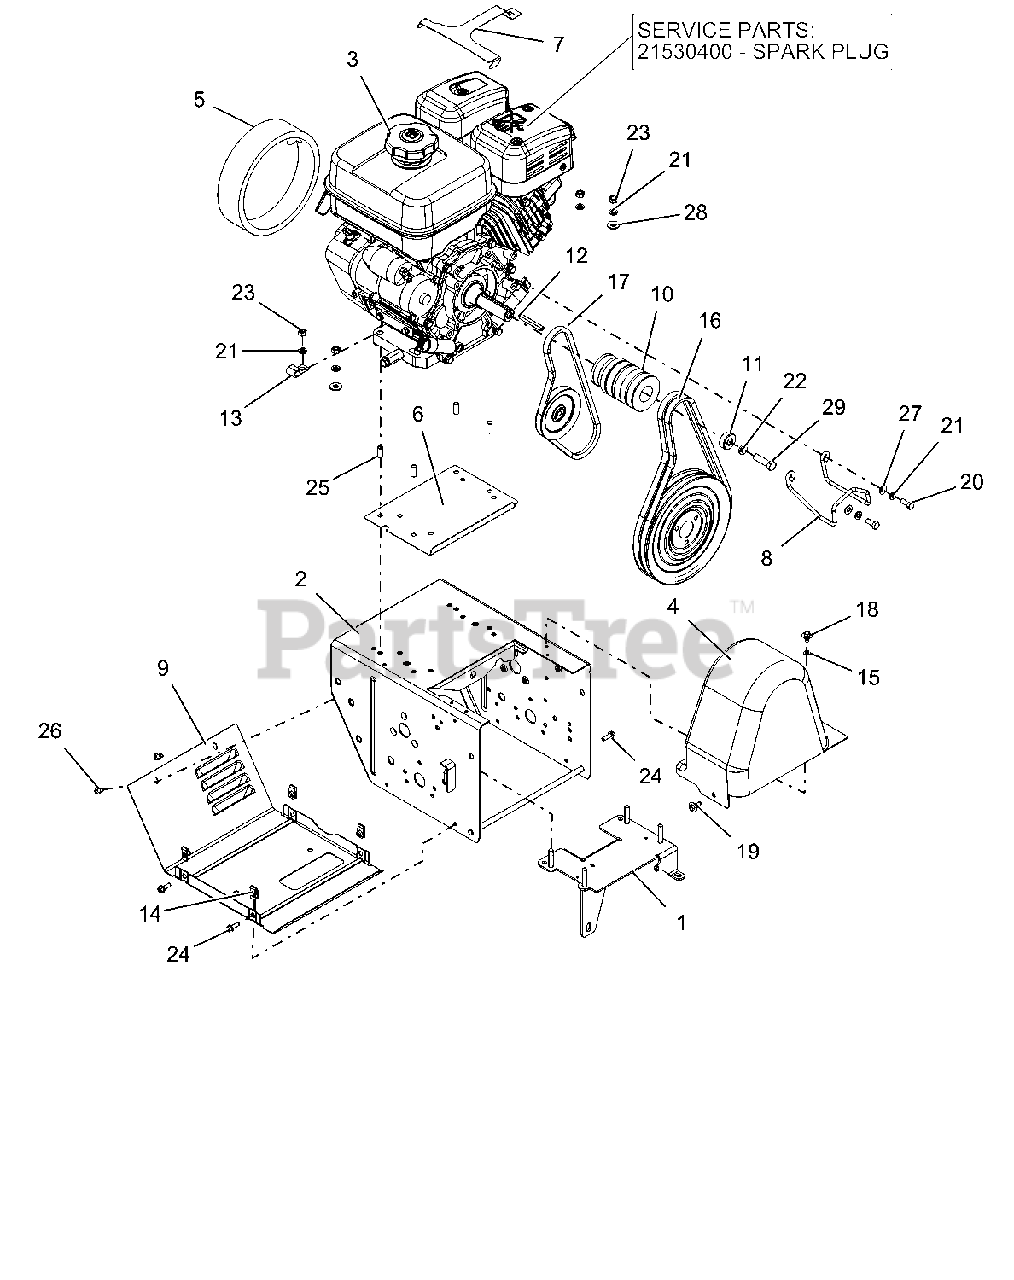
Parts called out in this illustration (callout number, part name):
1	BRKT, HYDRO TRANS LG
2	FRAME, MAIN - PRO SNOW
3	PLUG, SPARK - TEC. SNO-THRO
3	ENGINE,SUBARU EX30 AS 12V
4	COVER, BELT-TALL PRO
5	FOAM COVER, RECOIL-SUBARU
6	BAFFLE, WATER-PRO SERIES
7	GUARD, SNOW-SUBARU
8	FINGER, BELT
9	COVER, BOTTOM - VENTILATED
10	SHEAVE, COMBO HYDRO BRUSH
11	BSHG-SPACER .47X1.25X.50
12	KEY .25X.25X2.25
14	NUT-RTNR .25-20X.56
15	NUT-PUSH .25X.50 O.D.
16	V-BELT, HA-RAW EDGE (SET)
17	V-BELT, 4L-WRAPPED
18	SCR-TAP .25-20X.50 LGHWH TR YZ
19	SCR-TAP .25-20X.5 CAPTIVE
20	BLT-HEX .31-24X.75 YWZC GR5
21	WSHR-LK .312X.097 HVY YWZC
22	WSHR-LK .44X.109 REG YWZC
23	NUT-HEX .31-18 YWZC
24	BLT-HEX .25-20X.75 HWH YZ GR5
25	BSHG-SLV .325X.400X.795
26	SCR-TAP .25-20X.50 HWH TR YWZ
27	WSHR-FL-STL.344X.688X.065YWZC
28	WSHR-FL-STL.38X.875X.083 YWZC
29	BLT-HEX .44-20X1.50 G5 YZ EP80
